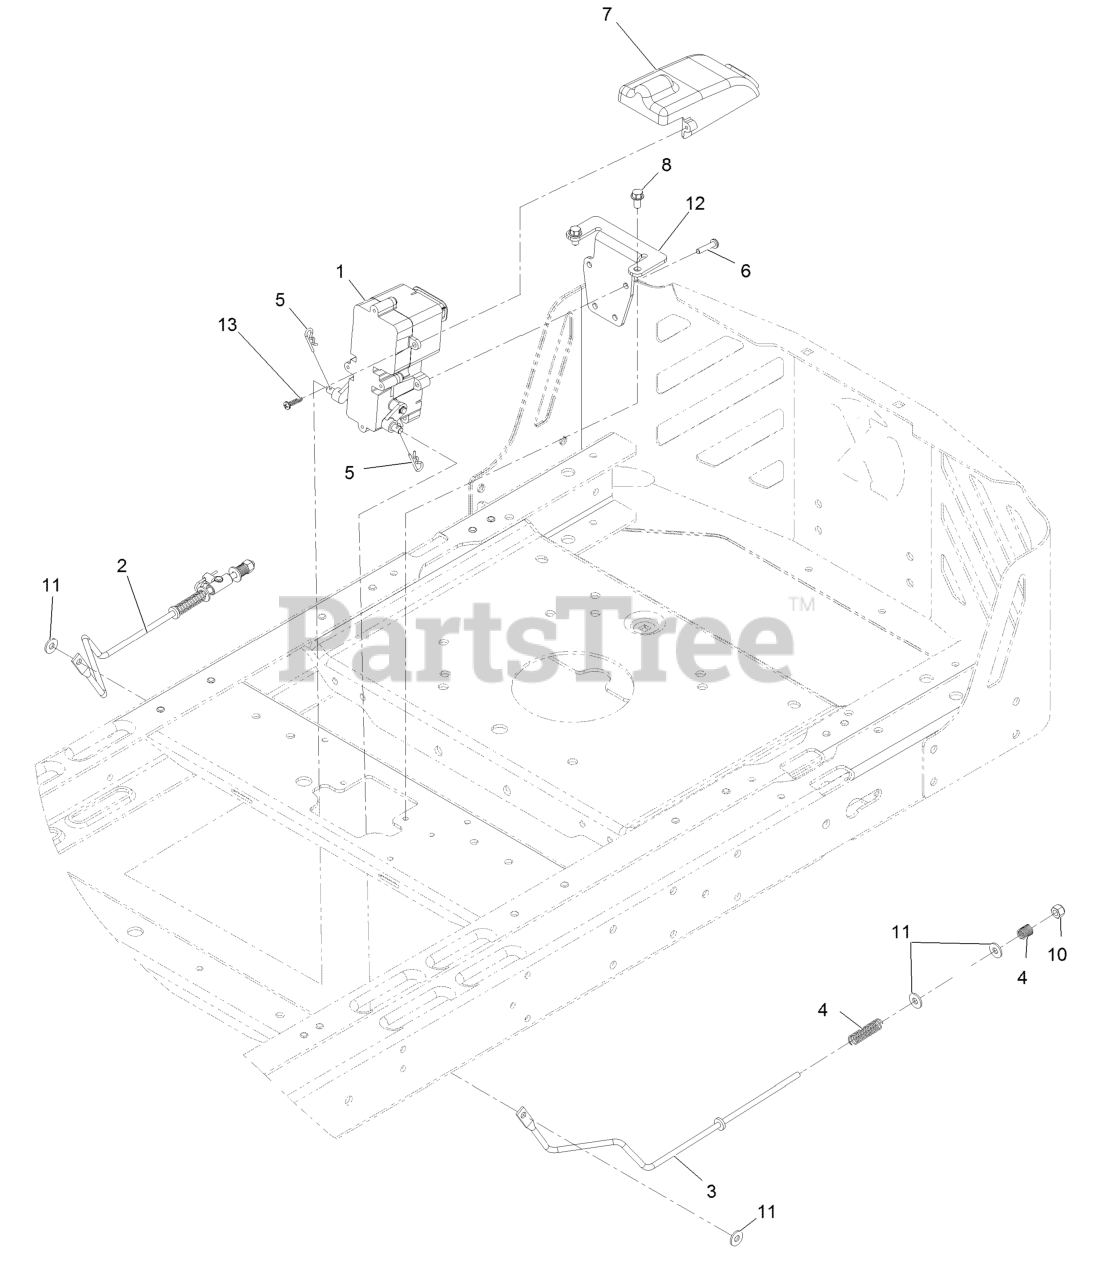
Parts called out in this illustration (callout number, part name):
2	ROD-BRAKE, RH
3	ROD-BRAKE, LH
4	SPRING-COMPRESSION
6	SCREW-PPH
7	COVER-CONNECTOR
8	SCREW-HWH
10	NUT-LOCK, NI
12	BRACKET-MOUNT, BRAKE
13	SCREW-PPH
